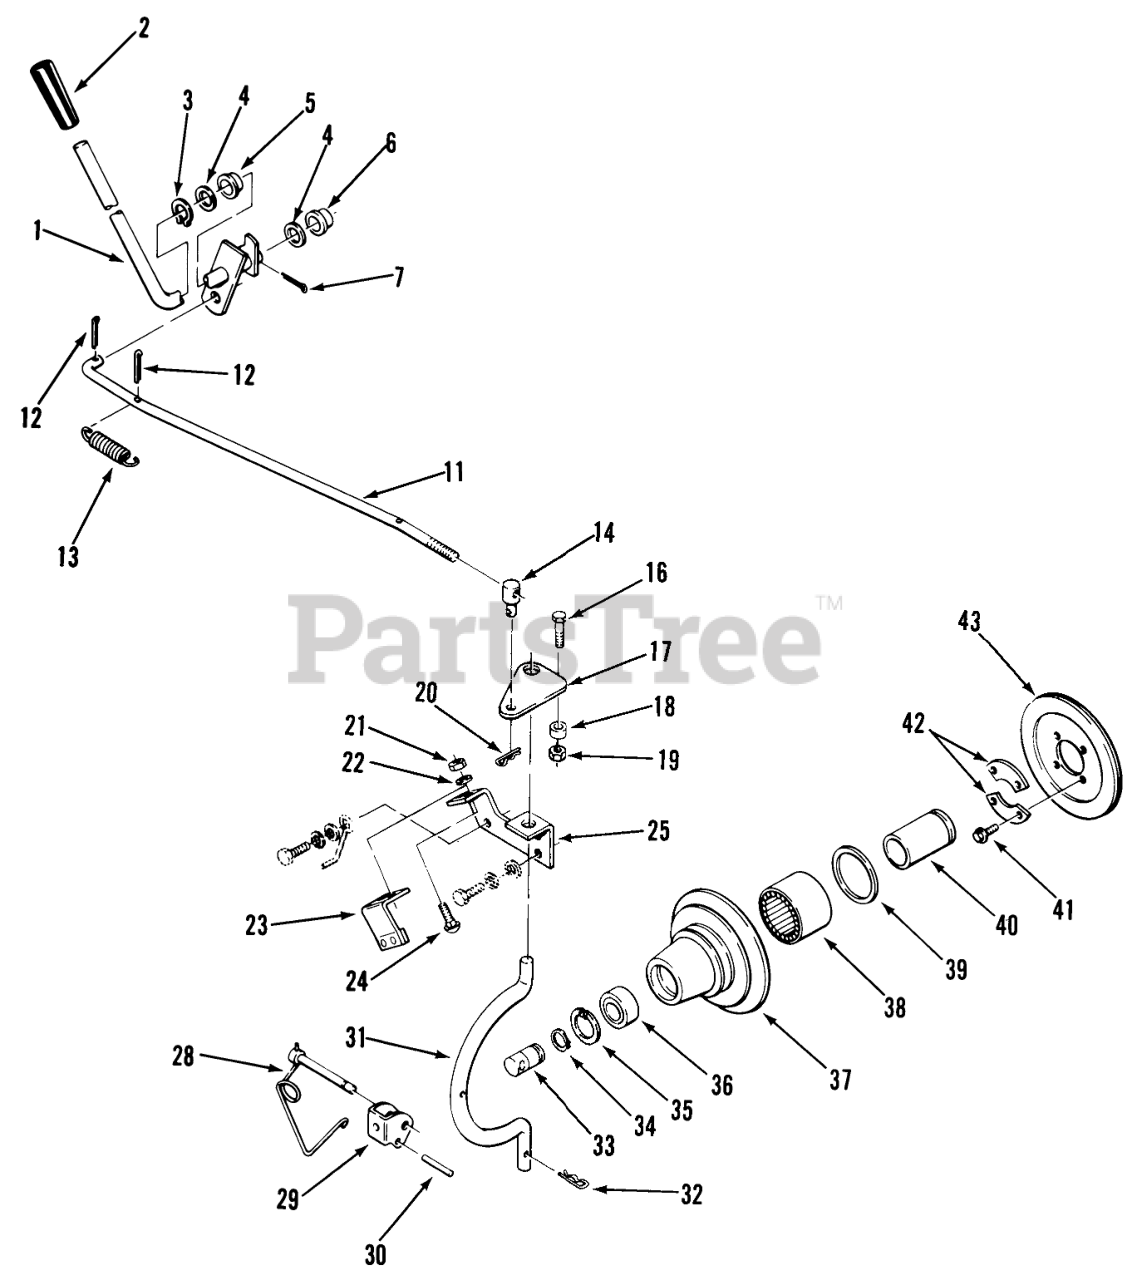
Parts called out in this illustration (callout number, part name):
1	PTO Clutch Lever
2	GRIP
3	Grip Ring
4	SHIM-WASHER
5	BUSHING-NYLINER
6	NYLINER BUSHING
7	Pop Rivet
11	PT0 Clutch Rod
12	Pop Rivet
13	SPRING
14	TRUNNION
16	BOLT
17	PTO Plate
18	SPACER-BRAKE LINK
18	SPACER-LIFT LINK
19	Nut
20	Hairpin Cotter
21	Nut
23	ASSY-BRAKE
23	PTO Brake Assy
24	Bolt-Carriage
25	BRACKET-ENGINE B
28	Pin
29	Clevis
30	PIN-SPIROL
31	ROD-HOUSING (NS)
31	ROD-HOUSING
32	Hairpin
33	SHAFT-PTO
34	RING-SNAP, EXTERNAL
35	Ring-Snap
36	BaIl Bearing
37	Housing-Clutch
38	BRG-NEEDLE OPEN END
39	SEAL-OIL
40	BEARING RACE
41	Screw
42	RETAINER
43	Clutch Plate & Facing
